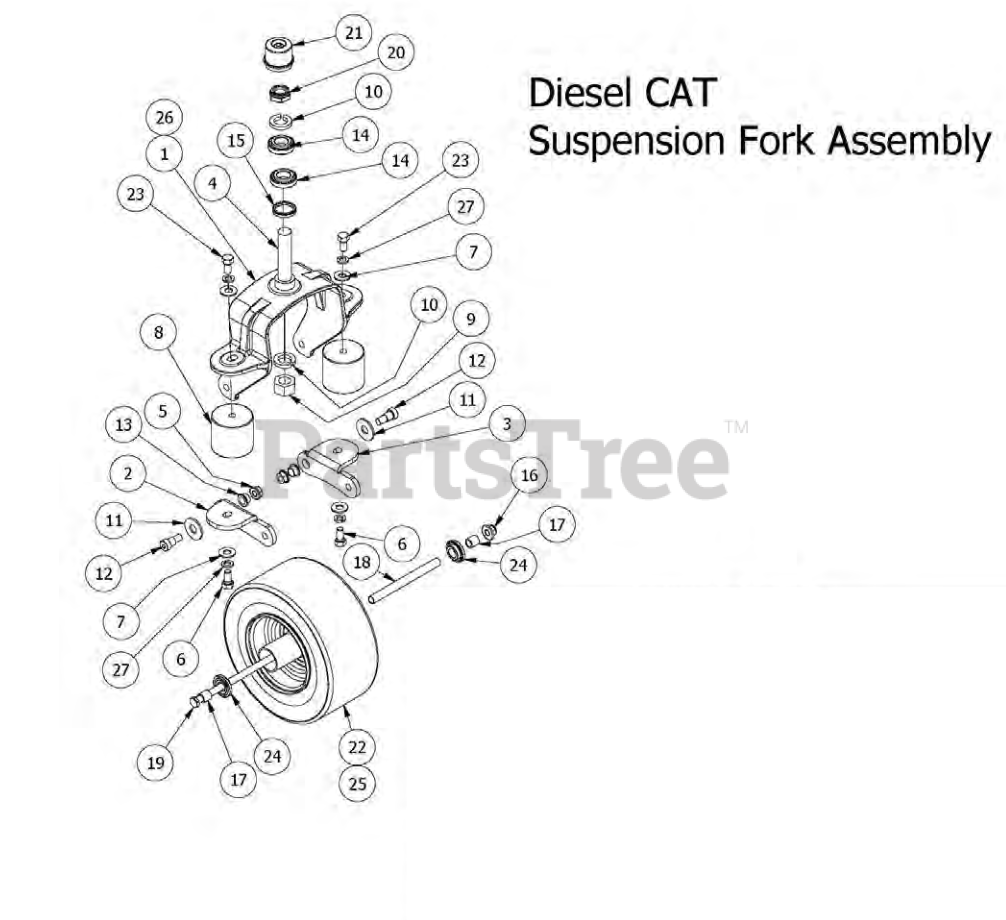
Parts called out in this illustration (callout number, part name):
1	Suspension Fork Top/Side Combo
2	Suspension Fork - Bottom Left
3	Suspension Fork - Bottom Right
4	Front Suspension Fork Spindle
5	1/2" Flange Nut
6	1/2" x 1" Hex Bolt
7	1/2" Washer (Grade 8)
8	Vibration Mount Red Dot
9	1" Fine Thread Nut
10	1" Lock Washer
11	5/8" Flat Washer
12	5/8" x 5/8" Shoulder Bolt
13	Bronze Bushing - SF-2024-8
16	1/2-13 Nylon Flange Nut
17	Spacer 3/4 OD x 1/2 ID x 314 Length
18	Front Wheel Spanner
19	1/2" x 10" Bolt
20	1" Fine Thread 1/2 Nylock Nut
21	Dust Cover
22	13 x 6.50-No-Flat Large Bore Orange front Assembly
23	1/2" x 1-1/4" Gr5 Hex Bolt (Coarse)
24	1-3/4" Bearing-Large Bore Front Rim
25	13 x 6.50- Reliance No-Flat
26	Suspension Fork Assembly
27	1/2" Lock Washer
